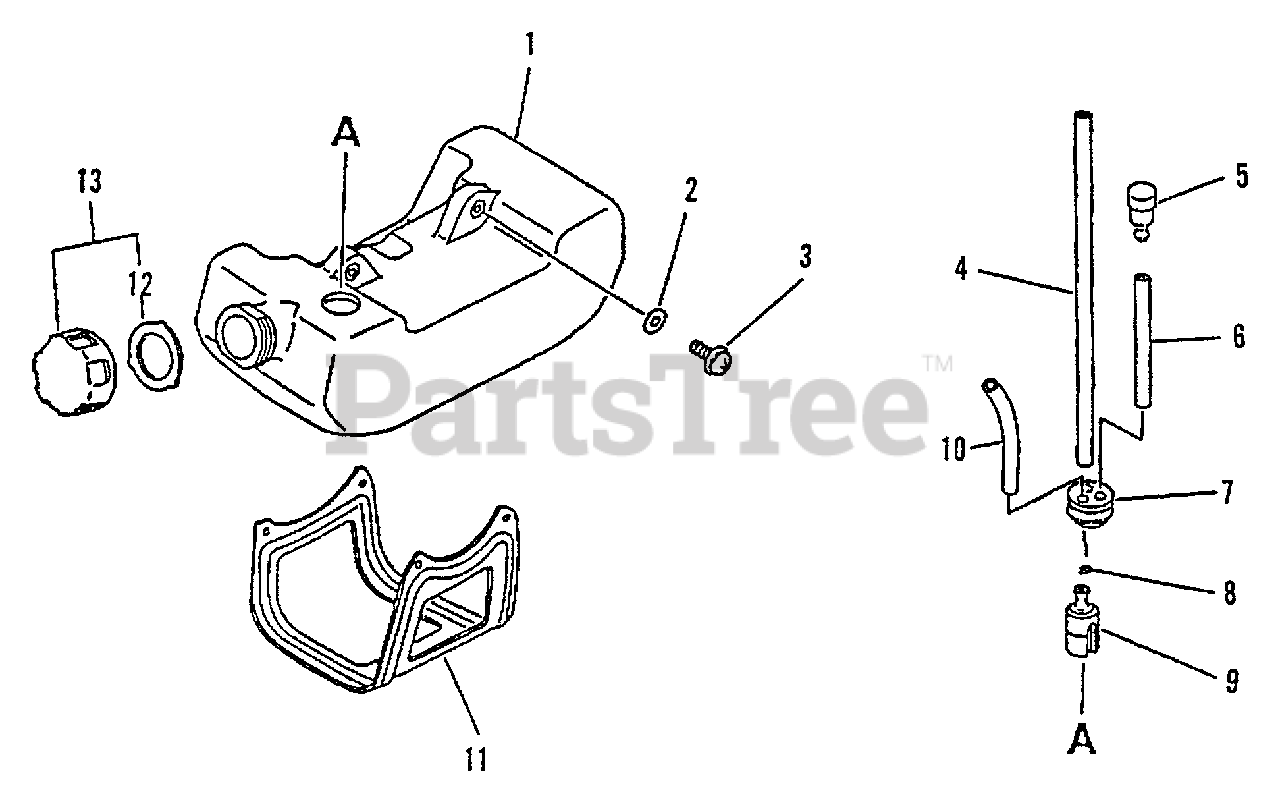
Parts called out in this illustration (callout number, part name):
1	TANK, FUEL
2	WASHER 5.5×12×0.8
3	SCREW 5×16
4	PIPE, FUEL 3x-5x-180
5	VENT ASSY
6	PIPE, FUEL 3x-5x-70 BLACK
7	GROMMET, FUEL
8	CLIP 6 MM
9	FILTER, FUEL
10	PIPE, FUEL RETURN 3×6×90 MM CLEAR
11	GUARD, FUEL TANK
12	GASKET, FUEL CAP
13	CAP ASSY
